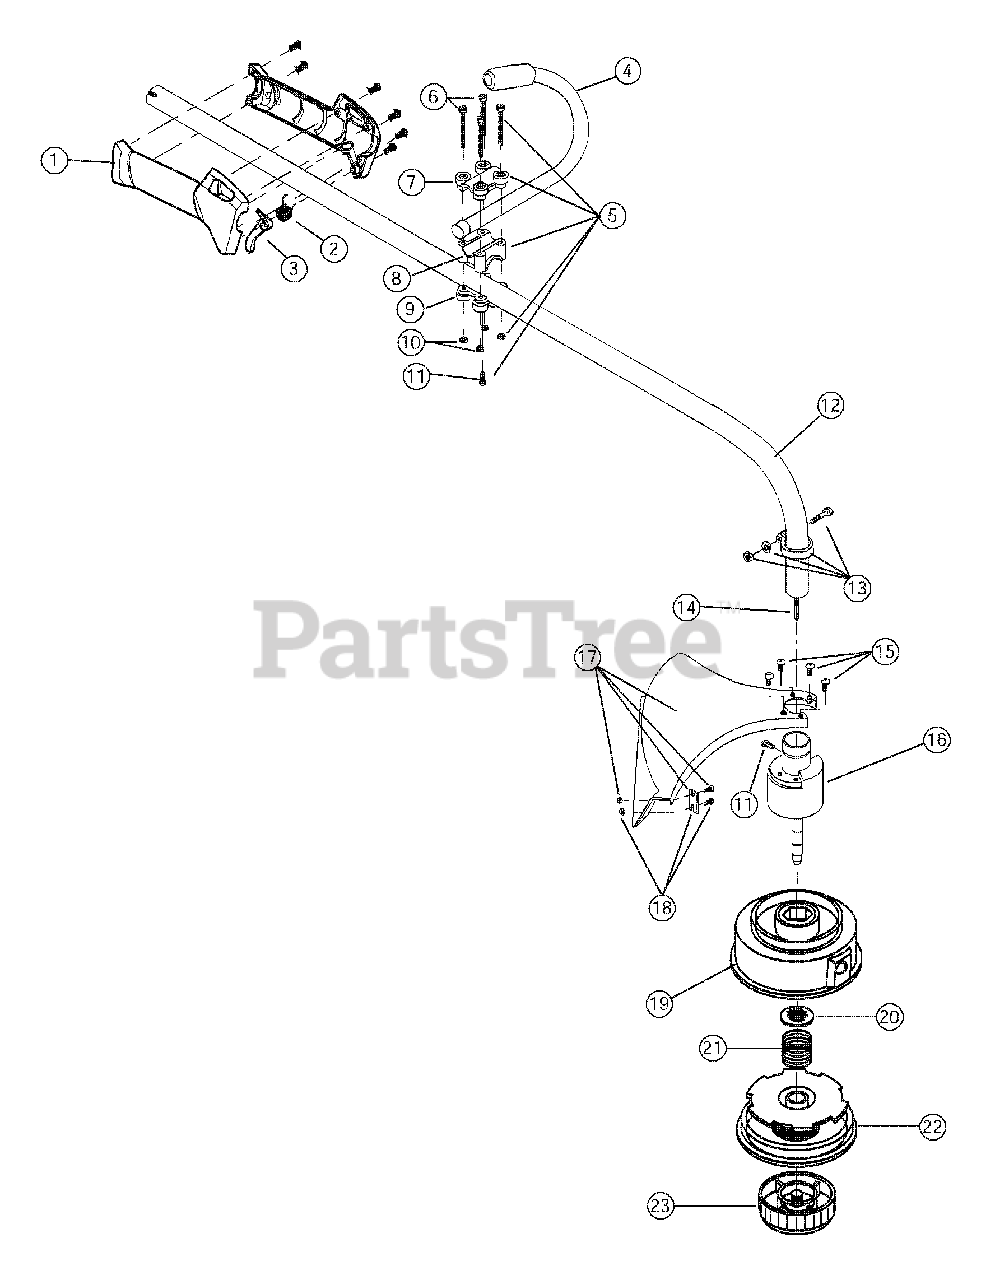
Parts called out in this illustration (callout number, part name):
1	Throttle Housing Assembly
2	Throttle Trigger Spring
3	Throttle Trigger
4	J-Handle Assembly
5	Handle Bracket Assembly
7	Upper Handle Clamp
8	Middle Handle Clamp
9	Lower Handle Clamp
11	Anti-Rotation Screw
12	Drive Shaft Housing Assembly
13	Lower Clamp Assembly
14	Flexible Drive Shaft
15	Shield Mounting Screw
16	Bushing Housing Assembly w/Spool Shaft
17	Shield and Blade Assembly
18	Blade Assembly
19	Outer Spool and Eyelet Assembly
20	Retainer
22	Inner Reel
23	Bump Head Knob Assembly
